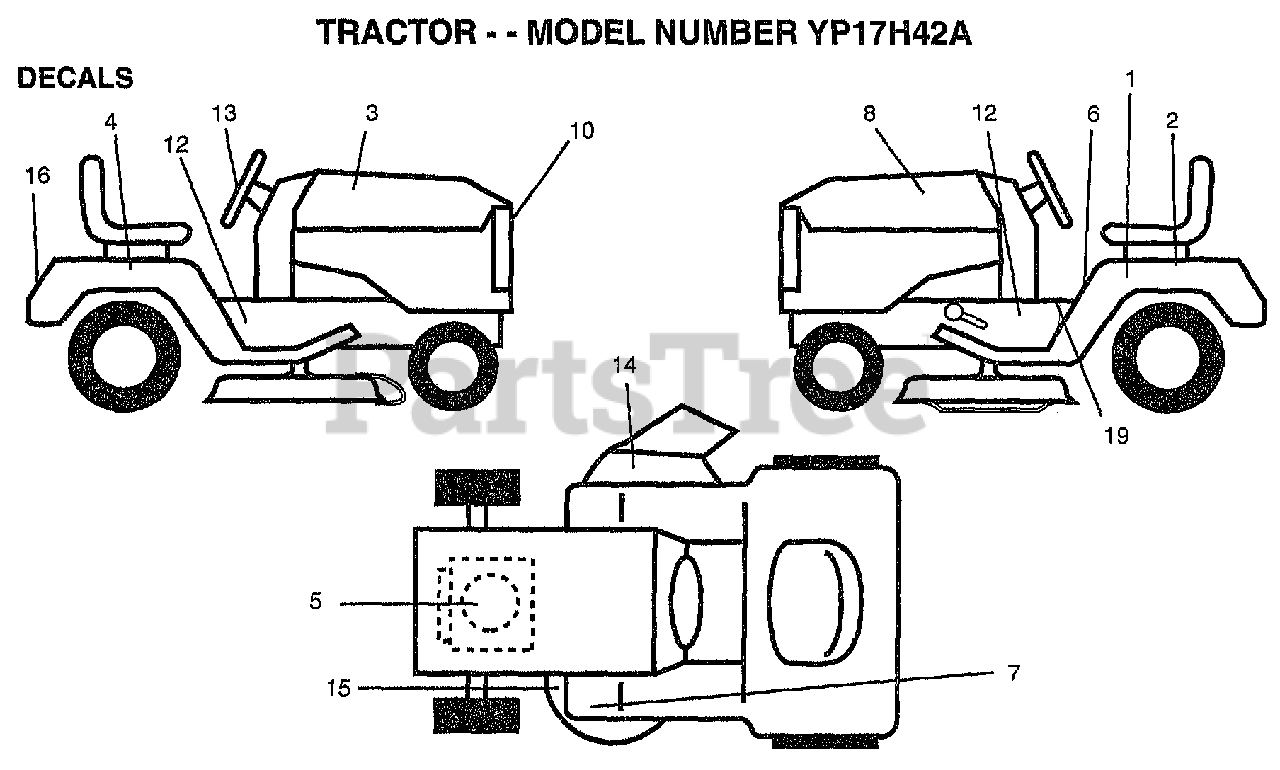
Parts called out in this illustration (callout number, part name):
1	DECAL.BATRY.3-3908
2	DECAL FENDER LH
3	DECAL
4	DECAL FENDER RH
6	DECAL.CAUT.ENG/FR
7	DECAL T
12	DECAL CHASSIS
13	DECAL INS STRG WH
14	"DECAL, WARNING"
15	"DECAL-SCHEM,BELT"
16	DECAL FENDER
19	DECAL SADDLE OPER
